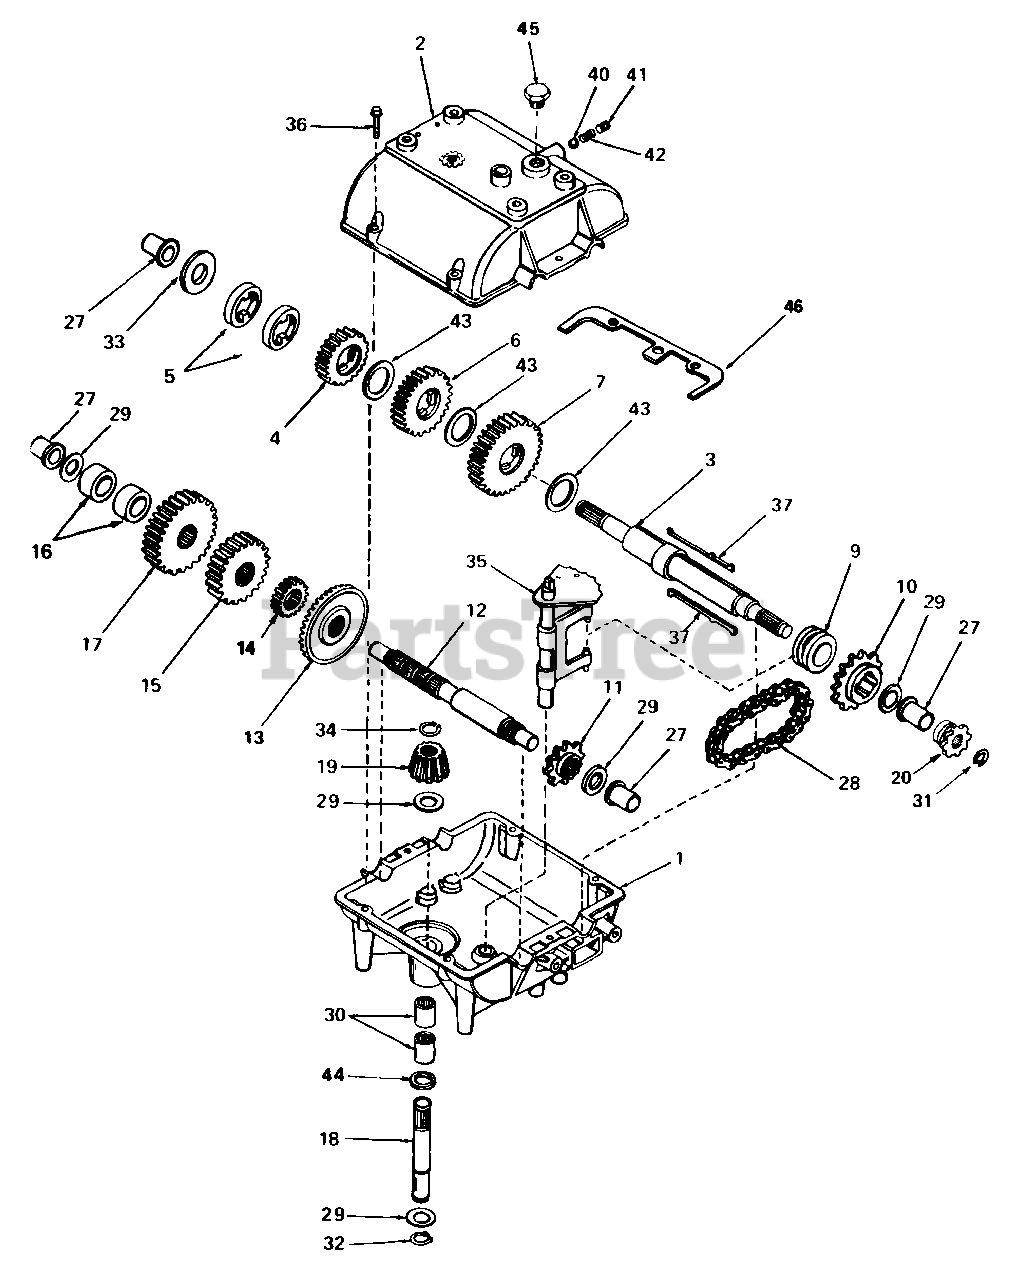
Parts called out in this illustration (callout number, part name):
1	CASE, Transmission
2	COVER, Transmission
3	SHAFT, Output & Brake
4	GEAR, Spur (25 Teeth)
5	SPACER, (1-3/8" O.D. x 1-1/8" I.D. x 3/8" Thick)
6	GEAR, Spur (30 Teeth)
7	GEAR, Spur (37 Teeth)
9	COLLAR, Shift
10	SPROCKET, (14 Teeth)
11	SPROCKET, (10 Teeth)
12	SHAFT, Counter
13	GEAR, Bevel (42 Teeth)
14	GEAR, Spur (12 Teeth)
15	GEAR, Spur (20 Teeth)
16	SPACER, (1-1/8" O.D. x 3/4" I.D. x 3/8" Thick)
17	GEAR, Spur (25 Teeth)
18	SHAFT, Input
19	BEVEL PINION, input
20	SPROCKET (8 Teeth)
27	BUSHING, Flanged
28	CHAIN, Roller (No. 41 ChaIN, 22 Links)
29	RACE, Thrust
30	BEARING, Needle
31	RING, Retaining
32	RING, Retaining
34	RING, Retaining
35	ROD & FORK ASSY., Shift
36	SCREW, Hex Hd., Taptite, 1/4-20 x 1-1/4
40	BALL, Steel, 5/16"
41	SCREW, Set, 3/8-16 x 3/8
43	WASHER, Thrust
